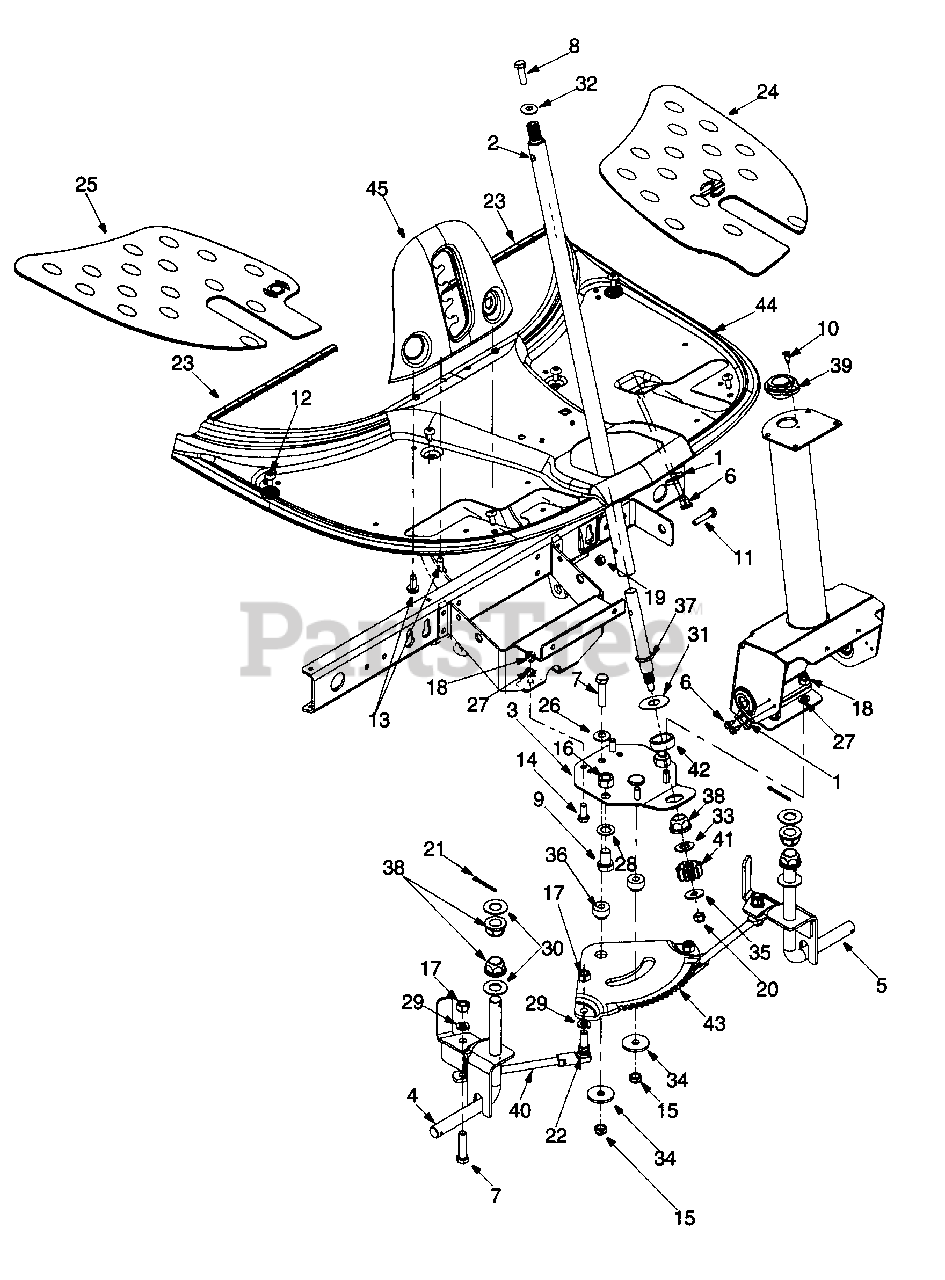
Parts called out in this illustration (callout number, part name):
1	Switch Plate
4	Front Axle Assembly: RH
5	Front Axle Assembly: LH
6	Hex Screw AB
7	Hex Screw 3/8-24 x 1.5" Gr. 5 Special
8	Lock Screw 5/16-18 x 1.0" Gr. 5
9	Hex Screw 1/2-13 x 0.75"
10	Oval Csunk Screw #10-16 x 0.625"
11	Hex Screw 1/4-20 x 1.25 Gr. 5 Special
12	AB Screw 1/4-14 x 0.625"
13	Self-Tapping Screw 5/16-18 x 0.75"
14	Hex Screw 5/16-18 x 0.75"
15	Lock Nut 3/8-24
16	Hex Nut 1/2-13
17	Hex Nut
18	Hex Nut
19	Lock Nut 1/4-20
20	Lock Nut
21	Cotter Pin
22	Ball Joint
23	Trim Strip
24	Floor Pad: LH
25	Floor Pad: RH
26	Bell Washer
27	Lock Washer
28	Flat Washer
29	Lock Washer
30	Flat Washer
31	Flat Washer
32	Belleville Washer
33	Flat Washer
34	Flat Washer
35	Flat Washer
36	Spacer
37	Steering Adapter
38	Hex Flange Bearing
39	Bearing: Steering Column
40	Tie Rod
41	Pinion Gear
42	Spacer
43	Gear: Steering Segment
